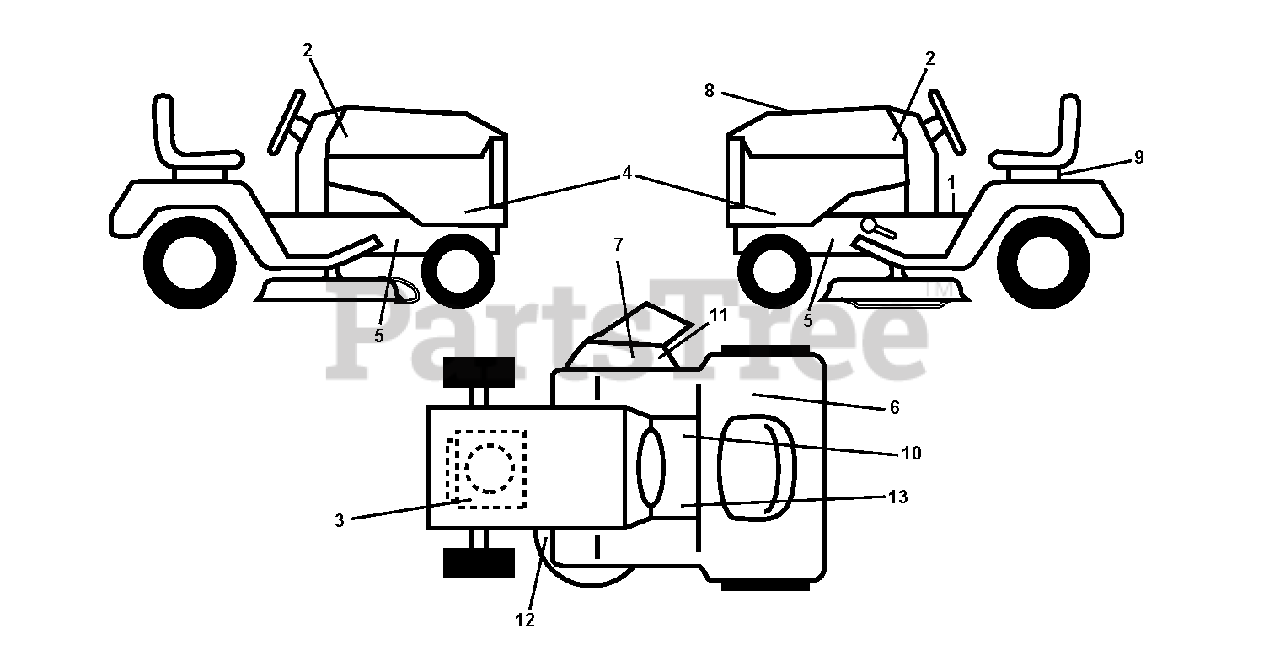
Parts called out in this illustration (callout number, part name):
1	LABEL
2	RP.DECAL.BADGE.170MM.TEXTLOGO
3	DECAL
6	Decal, Fender 100 DB/CE
7	DECAL.INTERNATIONL.CUTFINGER
8	DECAL
9	DECAL BTRY SYMBOLS
10	DECAL PARK BRAKE
11	DECAL, DEFLECT WARNING
12	DECAL V BELT SCHEMATIC
13	DECAL
